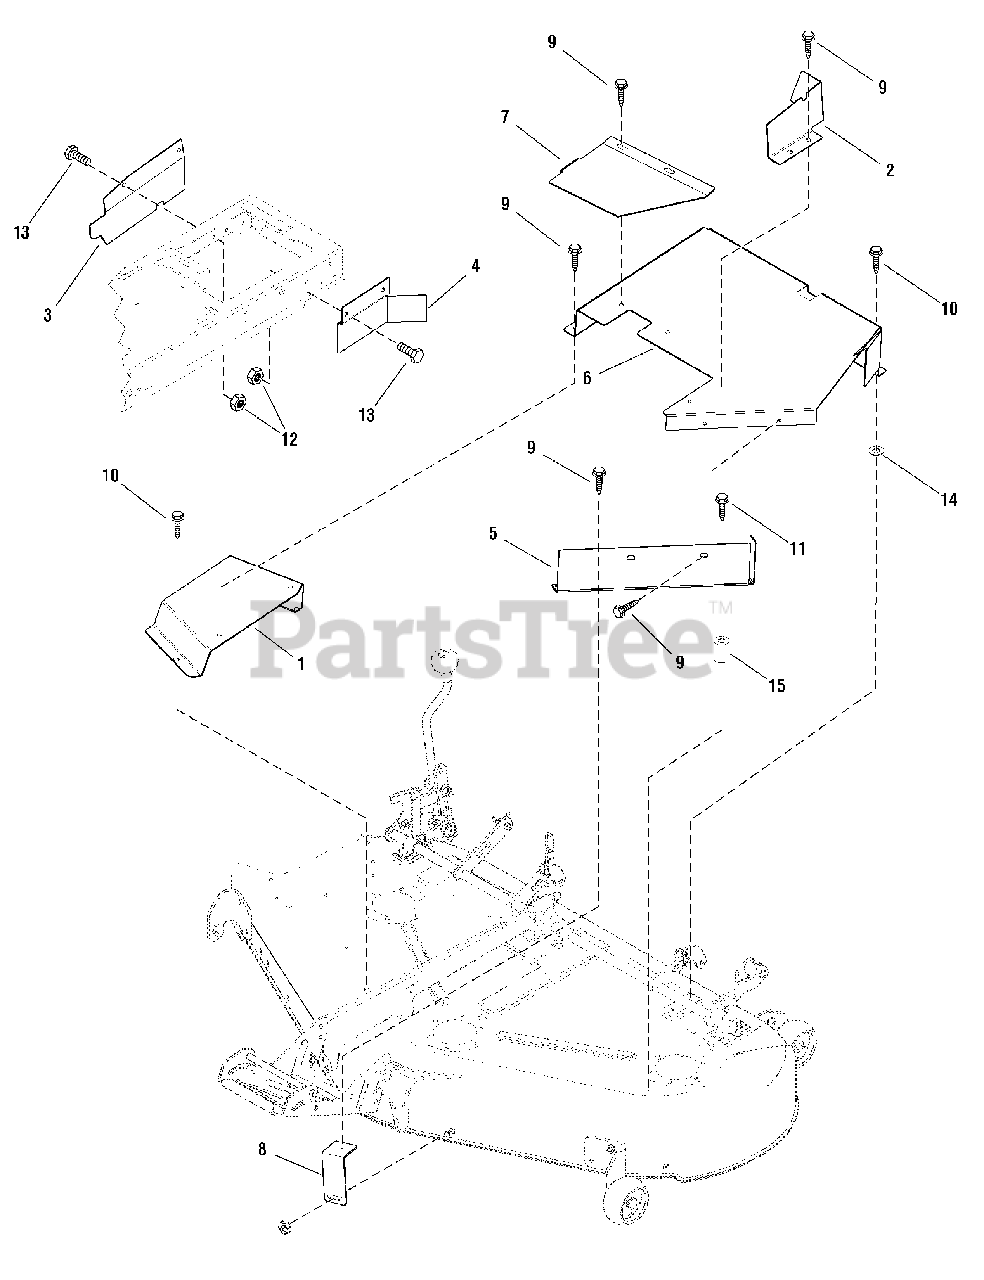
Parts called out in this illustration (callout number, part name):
1	GUARD, Belt, Right
2	GUARD, Belt, Rear
3	GUARD, Clutch, Right
4	GUARD, Clutch, Left
5	GUARD, Belt, Left
6	GUARD, Cover
7	GUARD, Clutch
8	BRACKET, Mounting
9	SCREW, Hex Washer Head, Taptite, 5/16-18 x 1/2
10	SCREW, Hex Washer Head Taptite, 5/16-18 x 3/4
11	SCREW, Hex Washer Head Taptite ,5/16-18 x 1-3/4
12	NUT, Hex Flange, 5/16-18
13	CAPSCREW, Hex Head, 5/16, 18 x 5/8
14	WASHER, 1
15	SPACER, 3/4
